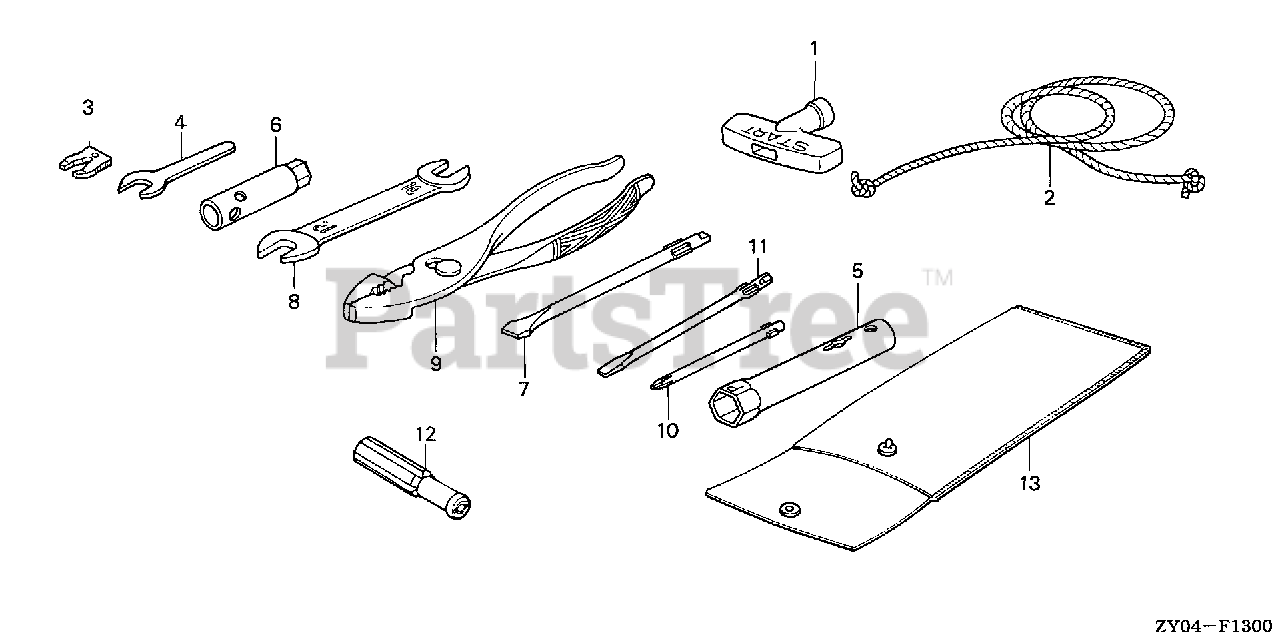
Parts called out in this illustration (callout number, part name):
1	GRIP, STARTER
1	KNOB, RECOIL SRARTER
2	ROPE, RECOIL STARTER (1300MM)
3	CLIP, EMERGENCY LOCK
4	SPANNER (8MM) (NOT AVAILABLE)
5	WRENCH, SPARK PLUG
6	WRENCH, BOX (10MM)
7	SCREWDRIVER, CHECK BOLT
8	SPANNER (10X12)
9	PLIERS (135) (KOWA)
9	PLIERS (135)
10	DRIVER 1, PLUS SCREW (NO.2)
11	DRIVER 3, MINUS SCREW (NO.2)
12	GRIP, SCREW DRIVER
13	BAG, TOOL (160MM)
